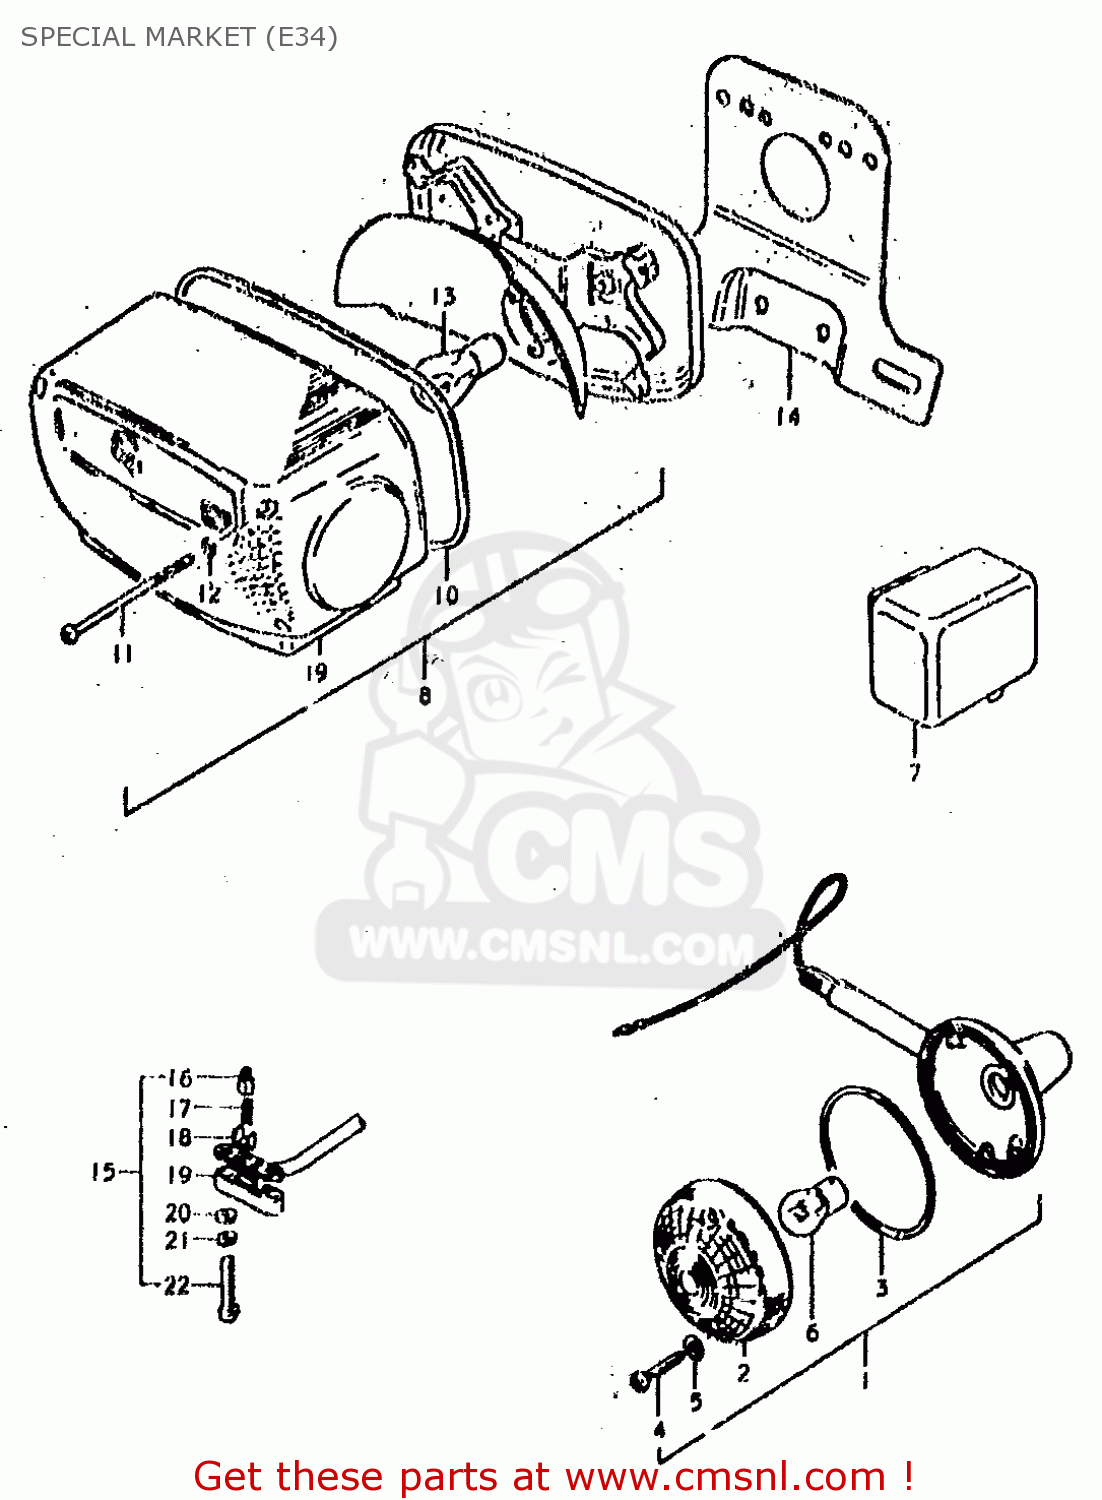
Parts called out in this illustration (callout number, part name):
1	LAMP ASSY, TURN SIGNAL
2	LENS
3	GASKET (NAS)
4	SCREW
5	GASKET (NAS)
6	BULB 12V 21W
8	LAMP ASSY,REAR COMBINATION
9	LENS
10	GASKET (NAS)
11	SCREW (4X55)
12	GASKET (NAS)
13	BULB(12V21/5W)
14	PLATE,LICENCE
15	SWITCH ASSY,STOP
16	HOLDER
17	SPRING
18	PLATE
19	COVER,FR BK TERMINAL BASE
20	WASHER
21	LOCK WASHER
22	SCREW
